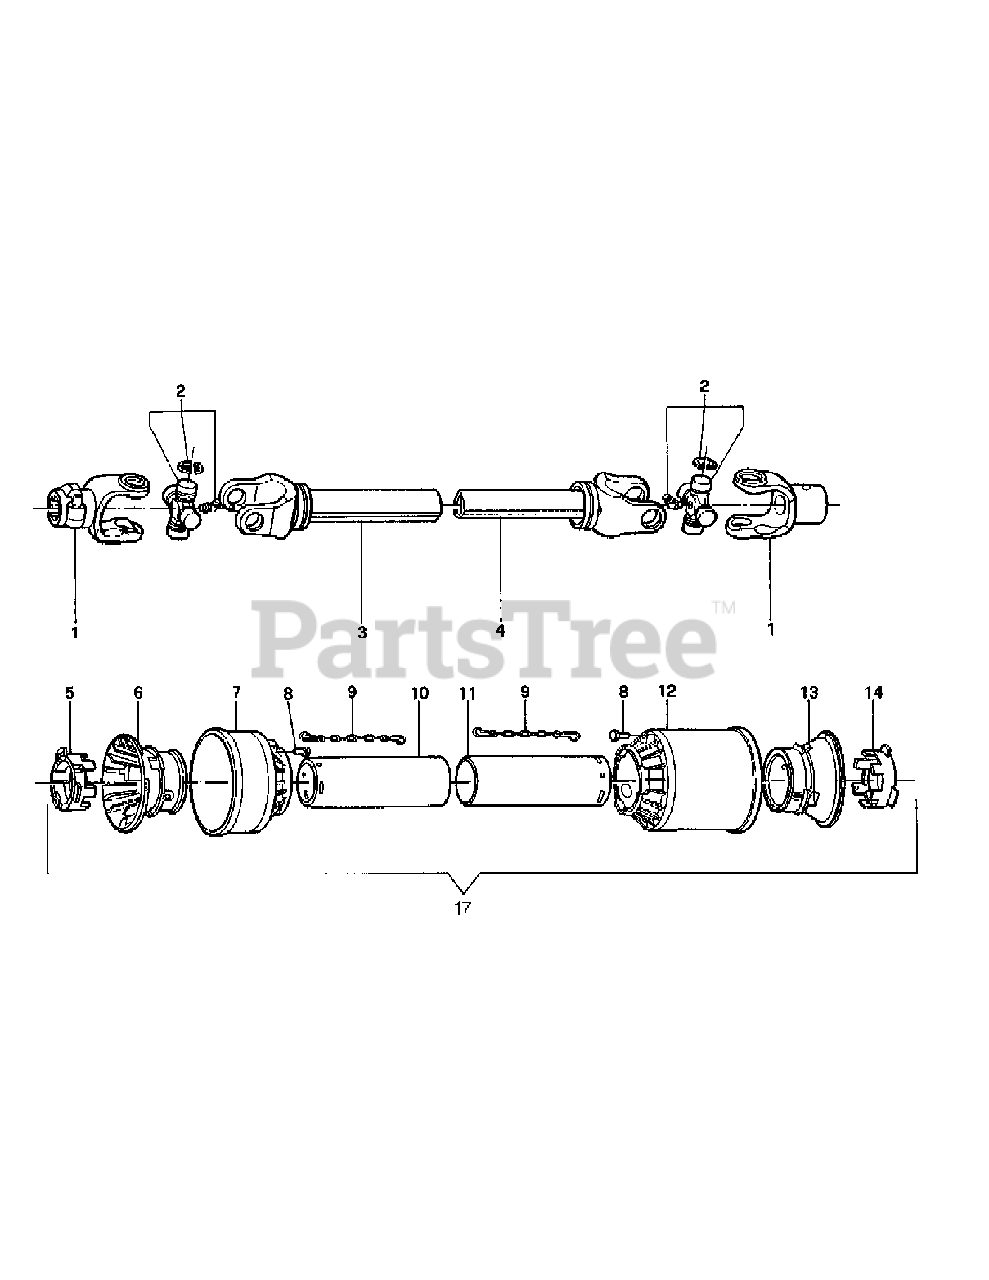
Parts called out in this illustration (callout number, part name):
1	PTO Yoke
2	Cross and bearing
3	Outer tube FML72
4	Inner tube FML72
5	Outer locking ring
6	Outer tube rigid cone
7	Outer cone (short)
8	Pin
9	Chain
10	Female tube shield FML72
11	Male tube shield FML72
12	Outer cone (long)
13	Inner tube rigid cone
14	Inner locking ring
